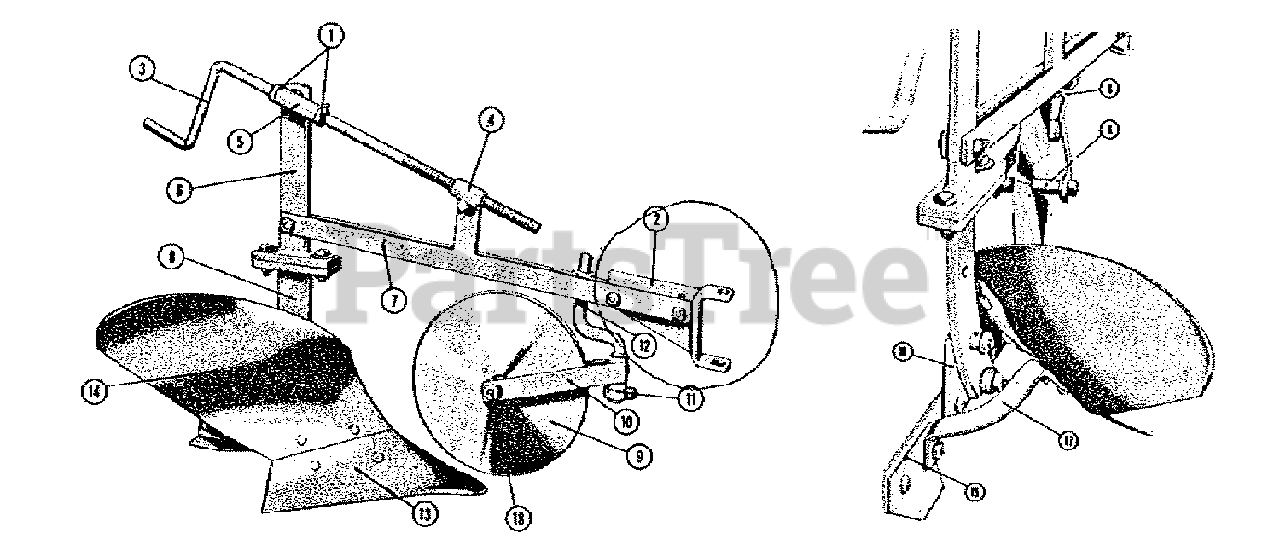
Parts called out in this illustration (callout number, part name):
1	SET COLLAR
2	BEAM END ASSEMBLY
3	DEPTH SCREW
4	ADJUSTING NUT ASSEMBLY
5	DEPTH SCREW BEARING ASSEMBLY
6	BEAM PIVOT ASSEMBLY
7	PLOW BEAM ASSEMBLY
8	STANDARD - Plow
9	COULTER WITH BUSHINGS
10	FORK ASSEMBLY
11	STOP ASSEMBLY
12	STANDARD - Coulter
13	10" PLOW SHARE
14	MOLDBOARD - 10" Plow
15	LANDSIDE w/DETACHABLE HEEL - 10" Plow
16	FROG - 10" Plow
17	SPREADER - 10" Plow
18	AXLE - Bolt
